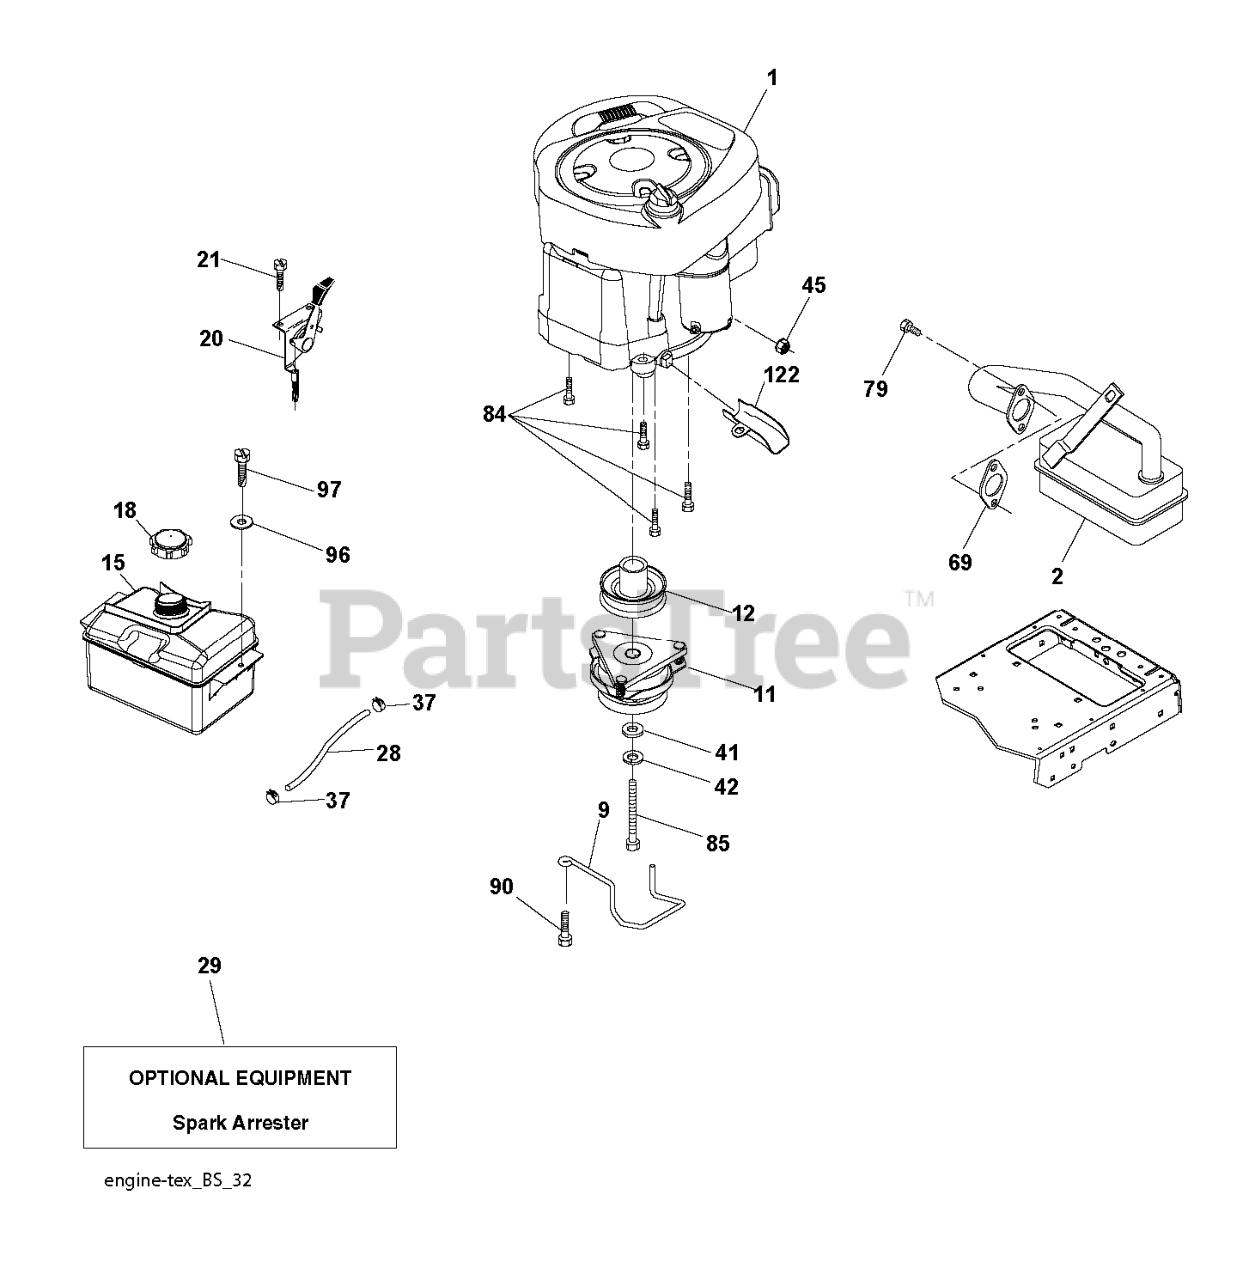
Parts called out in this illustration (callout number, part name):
2	MUFFLER.B&S.MODEL.21.11HP.OHV
9	KEEPER.BELT.ENGINE.3.25 (3 2)
11	RB.CLUTCH.OGURA.4.4.PD
12	PULLEY.ASM.ENG.OGURA.3
15	RP TANK FUEL FRT 1.5 GAL
18	CAP ASM.FUEL.2.25"FR.
20	CONTROL.TH/CK.C.
21	SCREW.#10 X 0.750.BOS
28	LINE.FUEL.20
29	KIT.SPARK ARRESTOR 794945 B&S
37	HOSE CLAMP
42	LOCKWASHER
45	NUT
69	REPL BY 532 27 22-93
79	SCREW.SOCKET HD.5/16-1
84	SCREW.3/8-16
85	BOLT HEX 7/16-20X4-1/4"
90	SCREW 3/8-16X1
97	SCREW HEXWSHR 1/4-20X3/4
122	EXTENSION DRAIN OIL
